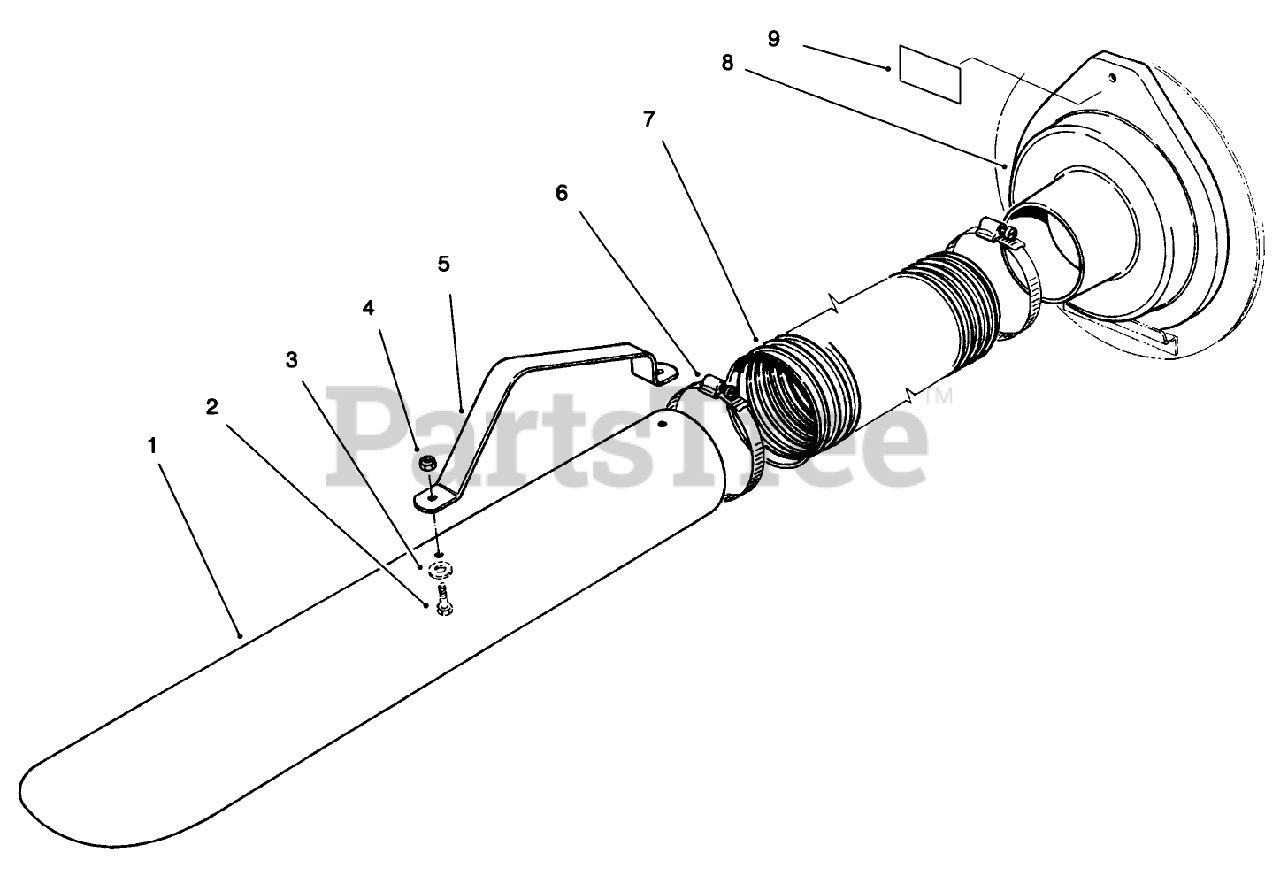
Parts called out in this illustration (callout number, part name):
1	NOZZLE
2	SCREW-HH
3	SPECIAL WASHER
4	NUT-KEPS
5	NOZZLE HANDLE
6	CLAMP
7	VACUUM HOSE
8	ADAPTOR HOSE TO HSG
9	DECAL-CAUTION, BAG
